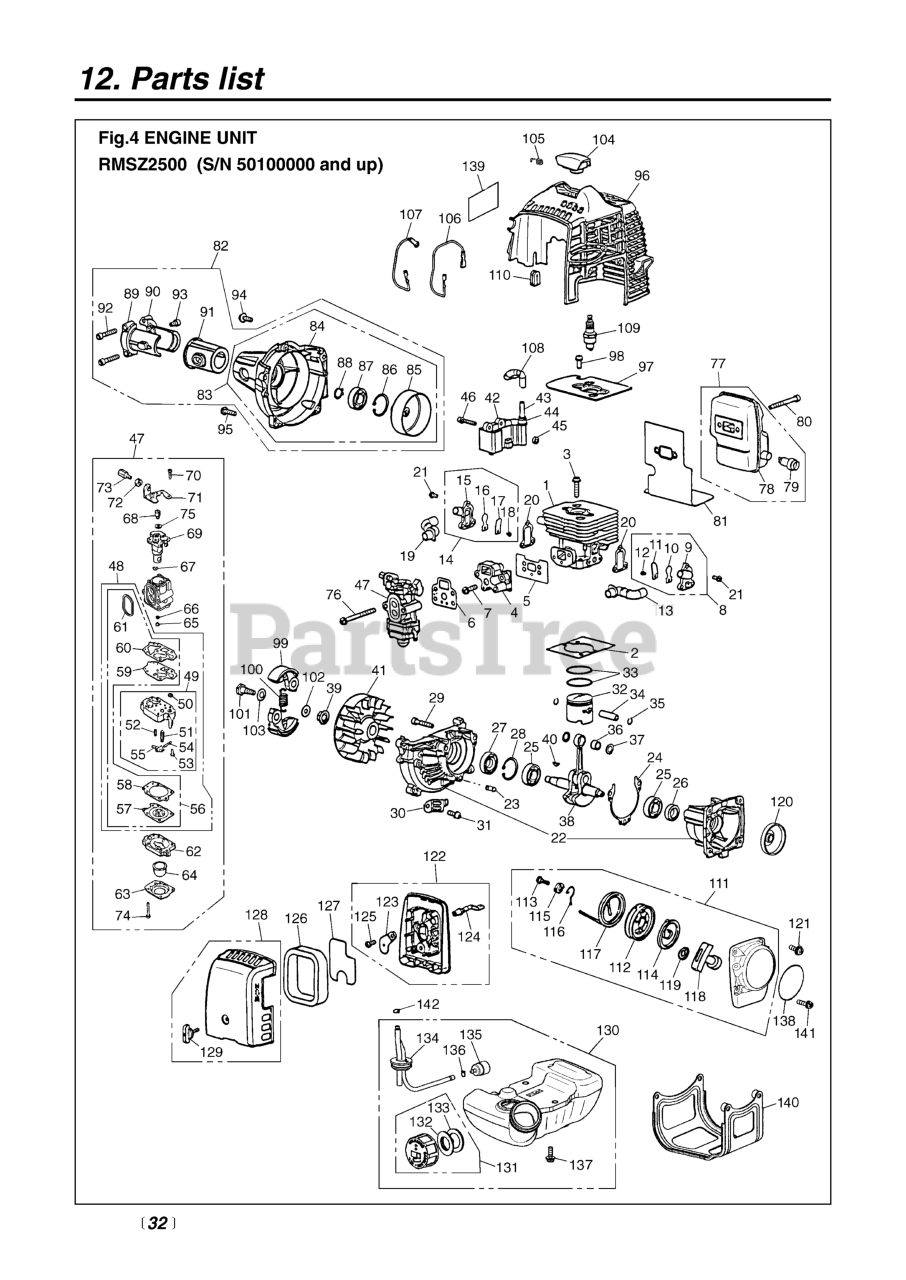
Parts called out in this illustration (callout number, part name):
1	CYLINDER (RPLS -12110)
2	GASKET, BASE
3	BOLT, M5 X 22
4	(REPLACES -13160)(USE -13162)
5	GASKET, INSULATOR
6	GASKET, CARBURETOR
7	SCREW, M5X20 (RPLS.1400-75510)
9	CASE VALVE
10	VALVE, REED
11	STOPPER
12	SCREW, M3 x 8
13	PIPE, AIR
16	VALVE, REED
17	STOPPER
18	SCREW, M3 x 8
19	PIPE, AIR (F)
20	GASKET, VALVE
21	SCREW
22	CRANKCASE COMP (USE 4810-21101
23	PIN
24	GASKET
25	BEARING
26	SEAL
27	SEAL, OIL (RPLS 1140-21220)
28	RING, SNAP, M28 x 1.2
29	BOLT, M5 X 30
31	SCREW, M5 X 10
32	PISTON
33	RING, PISTON
34	PIN, PISTON
35	RING, SNAP (RPLS 1101-41320)
37	WASHER
38	CRANKSHAFT COMPLETE
40	KEY
41	ROTOR
42	COIL-A
43	CORD
44	CAP
45	SPACER (RPLS -71260)
46	BOLT, M4 x 22
49	PUMP BODY ASSEMBLY
50	SCREEN
51	VALVE
52	SPRING
53	SCREW
54	PIN
55	LEVER
57	DIAPHRAGM
58	GASKET, DIAPHRAGM
59	DIAPHRAGM, PUMP
60	GASKET, PUMP
61	RING
62	BODY, PURGE
63	COVER, PUMP
64	PUMP, PRIMING
65	JET (USE -81251)
66	RING, O
67	RING
68	SWIVEL
69	VALVE
70	SCREW
72	NUT, CABLE ADJUSTER
73	SCREW, CABLE ADJUSTER
74	SCREW
75	WASHER
76	SCREW, M5 x 60
77	MUFFLER ASSEMBLY
78	MUFFLER (REPLACES -15110)
79	ARRESTER
80	BOLT, M5 x 50
84	COVER, FAN (USE -31111)
86	RING, SNAP, M28 x 1.2
87	BEARING
88	RING, SNAP (RPLS 3130-13270)
89	BRACKET (A) (RPLS -31210)
90	BRACKET (B) (REPLACES -31220)
91	CUSHION
92	BOLT, M5 X 30
93	BOLT (USE 3310-31720)
94	SCREW
95	SCREW, M5X20 (RPLS.1400-75510)
96	COVER, ENGINE (RPLS -32110)
97	PLATE
98	SCREW, M5 X 10
99	SHOE (RPLS 1100-51114)
100	SPRING
101	BOLT
102	WASHER, FLAT (USE 182303)
105	SPRING
106	CORD (BLACK)
107	CORD, EARTH (RED)
110	GROMMET
111	RECOIL ASSEMBLY
112	REEL
113	SCREW
114	SPRING, SPIRAL
115	COLLAR
116	ARM
117	ROPE (REPLACES 4500-75160)
118	KNOB (RPLS -75420)
119	PLATE, STOPPER
120	PULLEY
121	SCREW
122	BODY ASSEMBLY
123	PLATE, CHOKE
124	LEVER, CHOKE
125	SCREW
126	ELEMENT
127	SCREEN
128	COVER ASSEMBLY
129	KNOB (RPLS -82220)
130	TANK ASSY (USE -87001)
132	HOLDER (REPLACES -85230)
133	PACKING
134	PIPE COMPLETE
135	FILTER (RPLS 1850-85300)
136	CLIP (REPLACES 2841-31280)
137	SCREW
138	LABEL, RECOIL
139	LABEL, COVER (RPLS -31130)
141	SCREW, M5 x 25
142	CLIP
